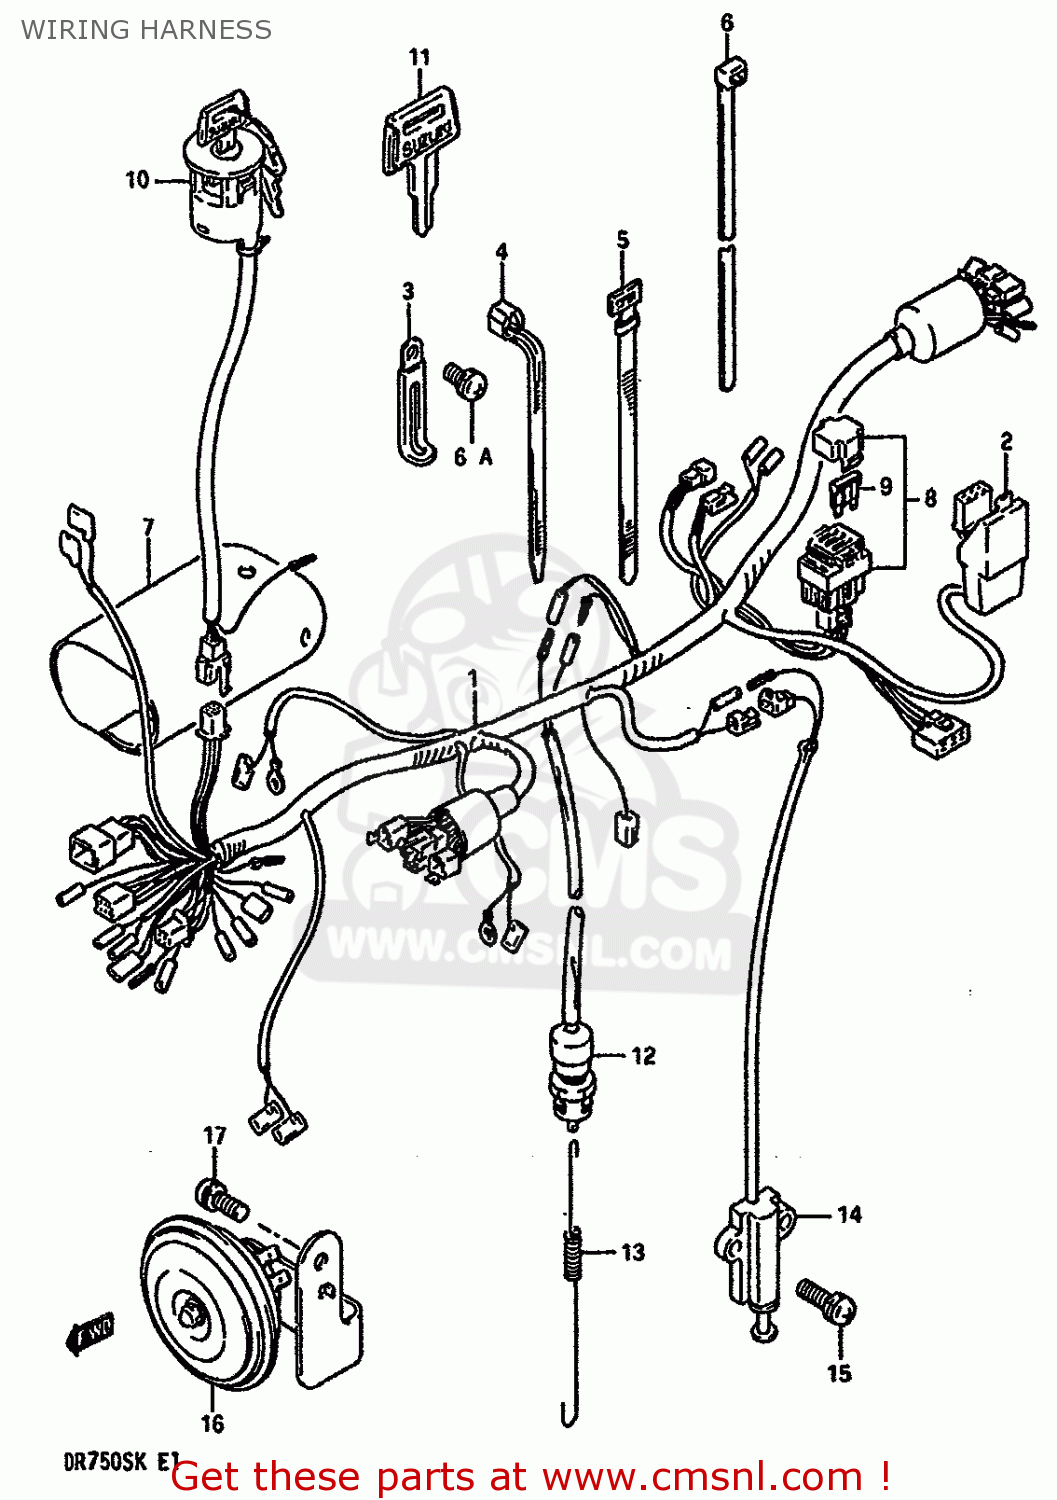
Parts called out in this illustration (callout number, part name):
1	HARNESS,WIRING
2	COVER,DECOMPRESSION CONTROL UNIT
3	CLAMP
4	CLAMP
5	CLAMP(L:125)
6	CLAMP(L:300)
6A	SCREW
7	COVER,WIRING HARNESS
8	BOX ASSY,FUSE
9	FUSE(15A)
10	SWITCH ASSY,IGNITION
11	KEY,BLANK
12	SWITCH ASSEMBLY,STOP LAMP
13	SPRING
14	SWITCH ASSEMBLY,SIDE STAND
15	SCREW
16	HORN ASSY
17	SCREW
